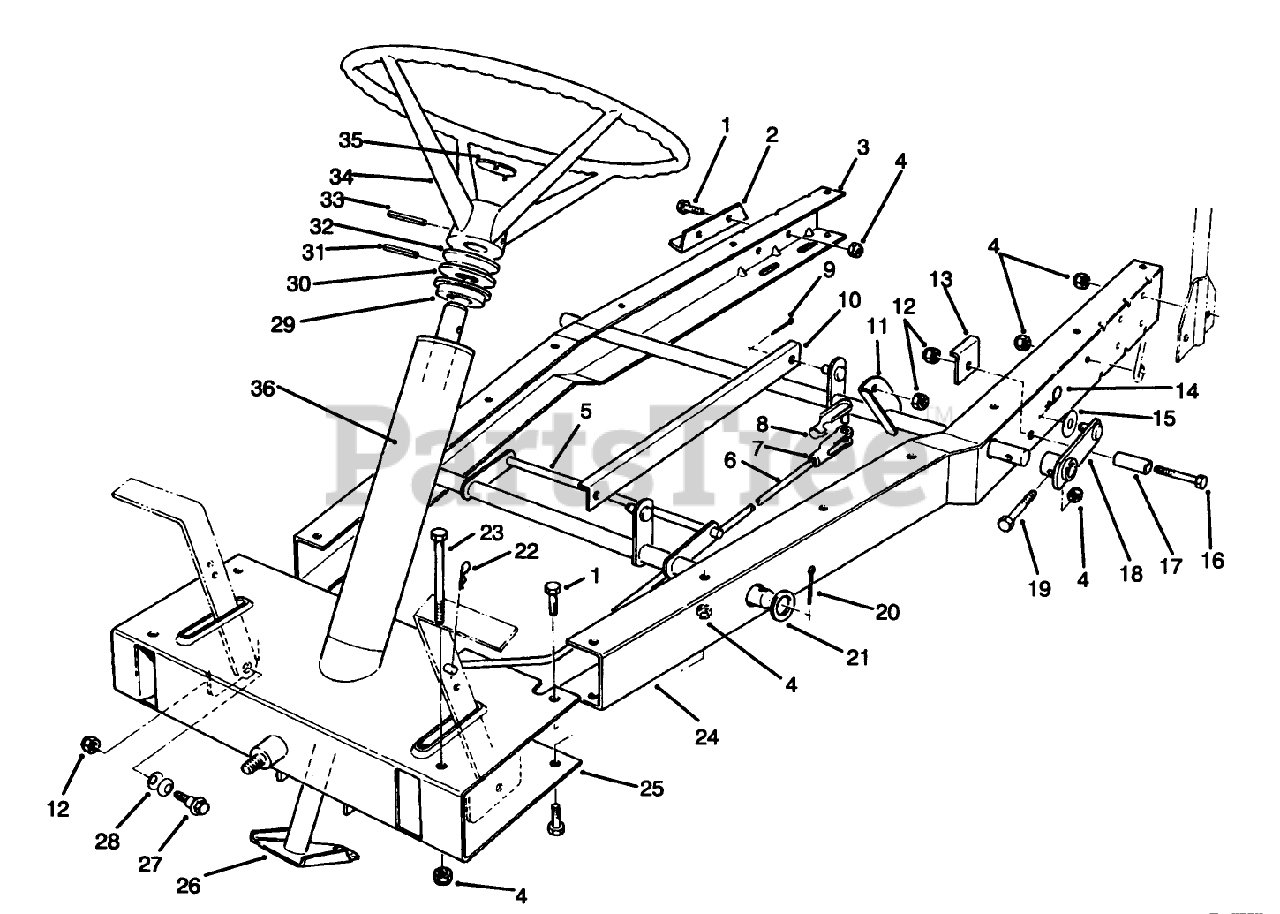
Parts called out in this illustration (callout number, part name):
1	SCREW-HH
2	MOUNT-AXLE BEARING
4	NUT-LOCK, NI
6	ROD-CLUTCH
7	CLEVIS-ADJ
8	Assembly-Pin, Clevis
9	PIN-COTTER
10	LINK-HOC BRACKET
11	TUBE ASM-REAR SUPPORT
12	NUT-LOCK, NI
13	DECK STOP BRACE
14	PIN-HAIR
15	WASHER
16	SCREW-HH
17	SPACER-STOP,DECK
19	AXLE MTG BOLT
20	PIN-COTTER
21	WASHER-FLAT
22	PIN-COTTER
23	SCREW-HH
24	FRAME-CHANNEL LH *
27	BOLT-SHOULDER
28	WASHER-BELLEVILLE
30	WASHER-STEERING
31	PIN-ROLL
32	SPACER-STEERING
33	PIN-ROLL
34	STEERING WHEEL ASM
35	INSERT - STEERING WHEEL, LAWNBOY
36	DECAL - STEERING COLUMN
